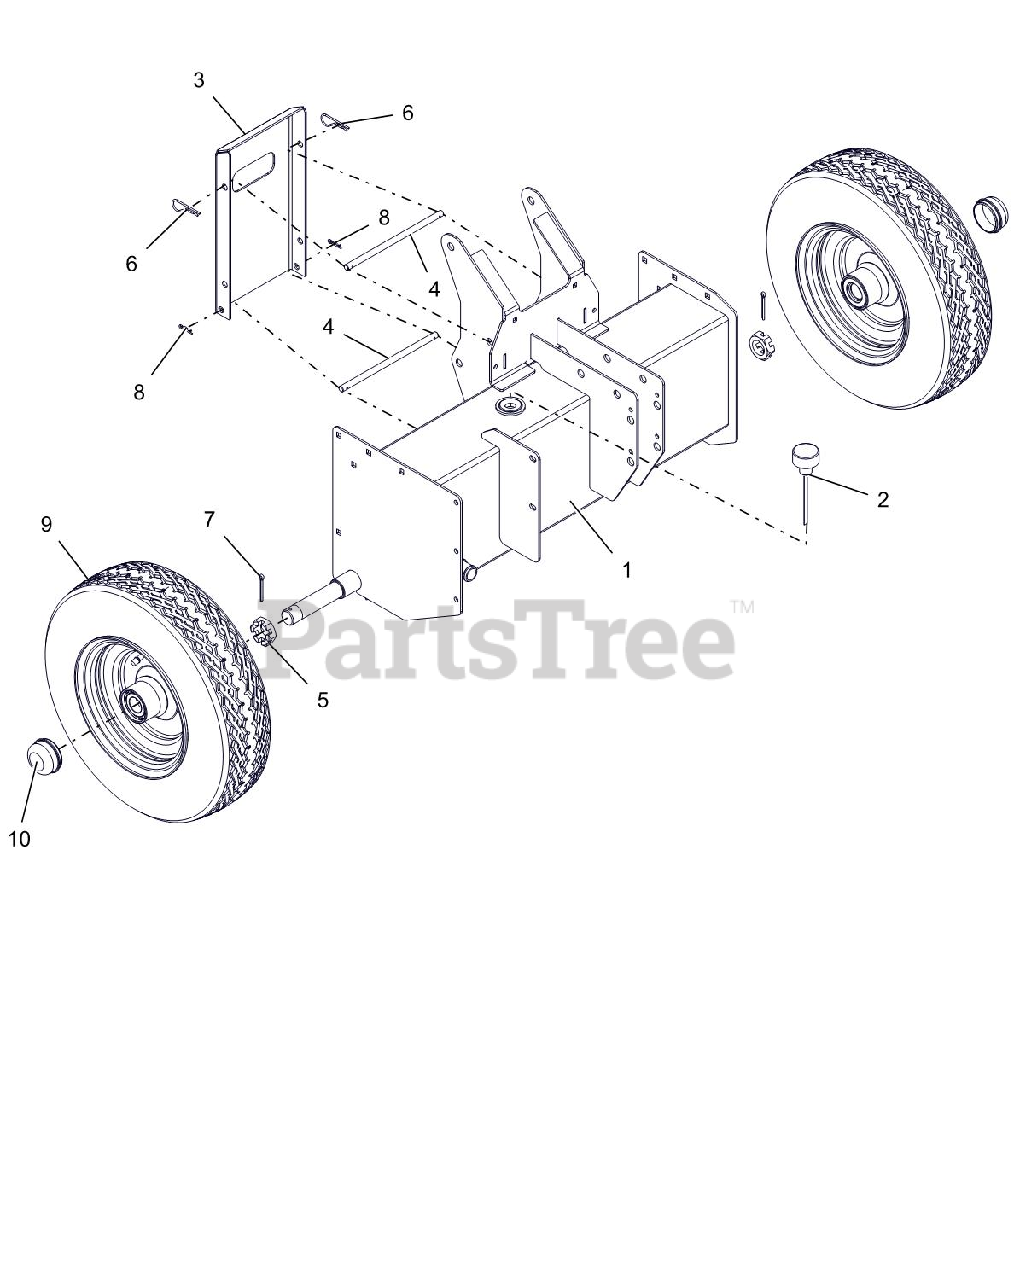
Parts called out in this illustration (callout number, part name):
1	CHASSIS-SPLIT W/SFTY DECAL-22T
2	BREATHER, DIPSTICK
3	REAR STAND W/DECALS (ARIENS)
4	PIN, .373 X 7.30 X 2X.109 THRU
5	NUT-SL 1.0-14
6	HAIRPIN, #7 CLIP .094X2.31 YWZ
7	@PIN-CTR .15X1.50 YWZC
8	PIN-HAIR, ENDRIES #25 YWZC
9	ASM,TIRE/WHEEL 4.8/4-8 P47GRAY
10	CAP, DUST
